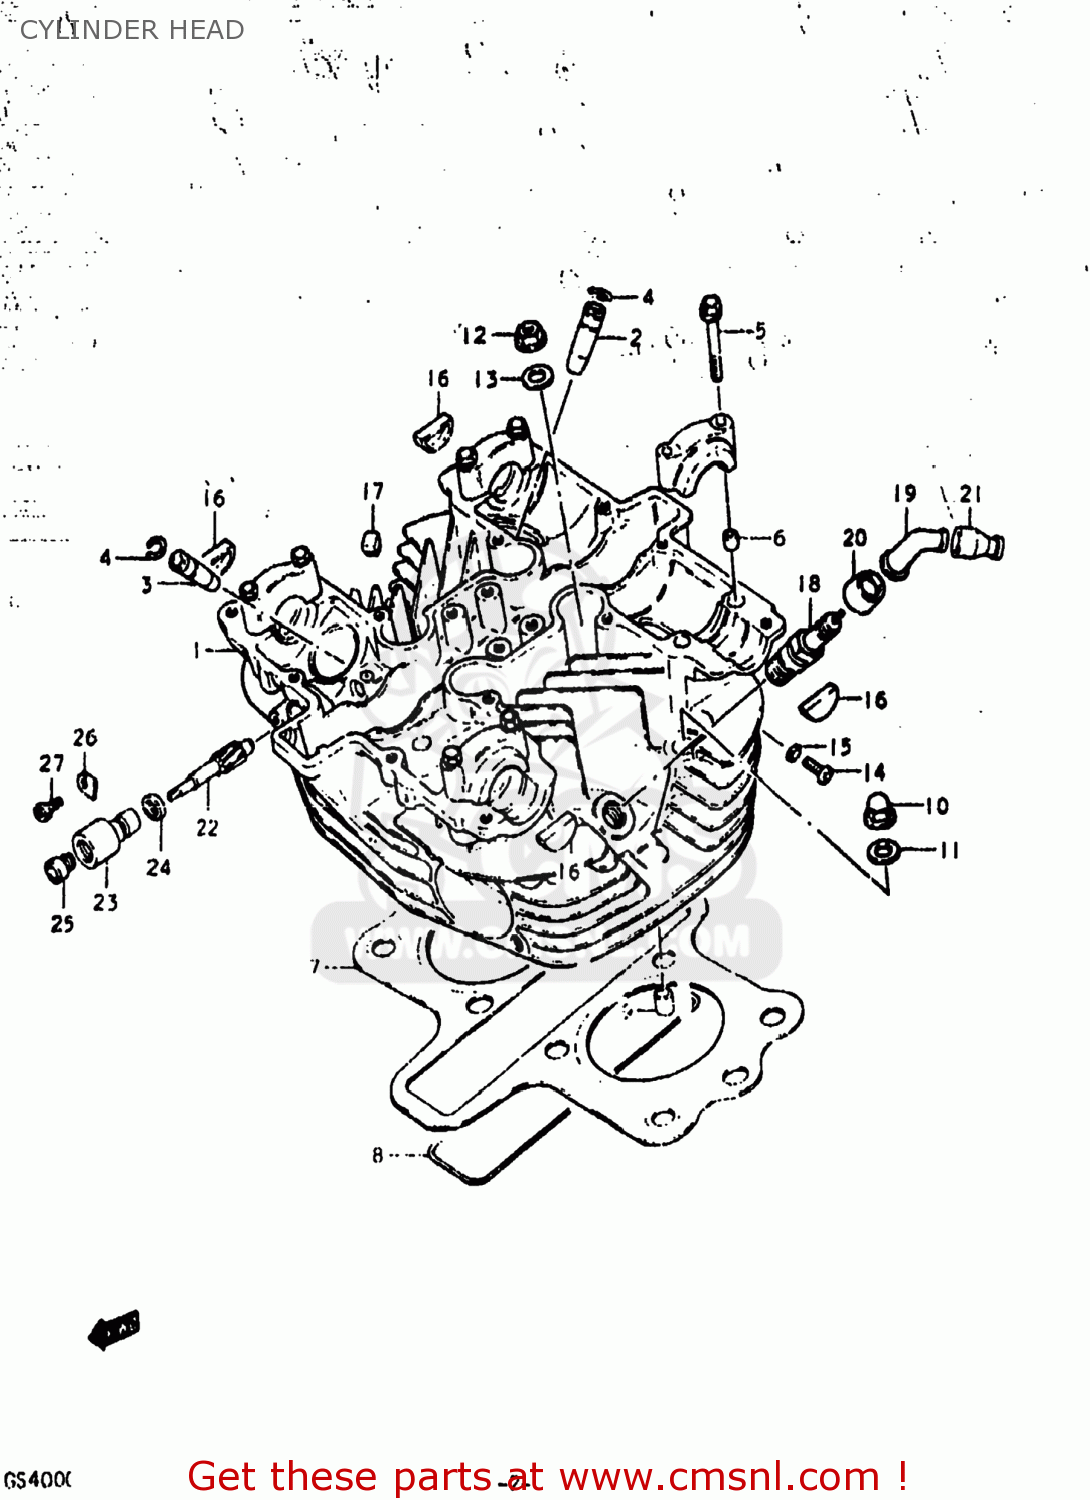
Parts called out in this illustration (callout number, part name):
1	HEAD ASSEMBLY,CYLINDER
2	GUIDE,VALVE
3	GUIDE,VALVE
4	RING,SNAP
5	BOLT(6X39)
6	PIN(6.2X8X11)
7	GASKET,CYLINDER HEAD (MCA)
8	O RING(D:3,ID:26X157)
9	PIN
10	NUT
11	GASKET(10.5X22X2) (NAS)
12	NUT
13	WASHER(10.5X22X2.3)
14	SCREW 5X20
15	GASKET(5.3X9.3X1.2) (NAS)
16	PLUG
17	PAD
18	PLUG,SPARK
19	CAP,SPARK PLUG
20	SEAL,SPARK PLUG
21	SEAL,SPARK PLU
22	GEAR,TACHOMETER DRIVEN
23	SLEEVE,TACHOMETER DRIVE
24	SEAL,TACHOMETER DRIVEN
25	SEAL
26	PLATE,TACH DRIVE GEAR SLEEVE
27	SCREW(5X12)
